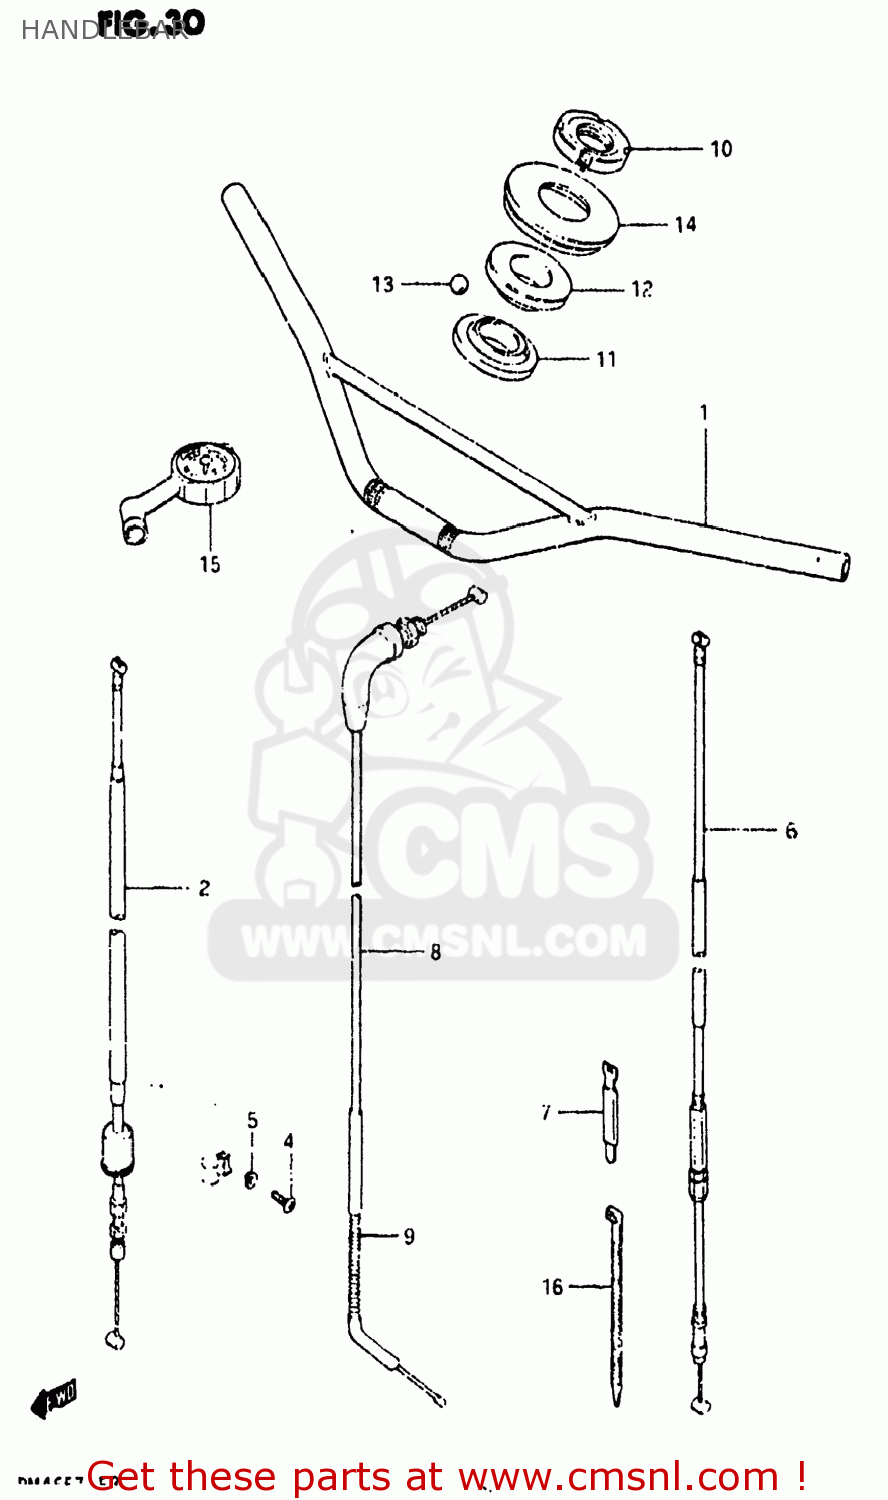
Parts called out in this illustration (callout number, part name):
1	HANDLEBAR
2	CABLE ASSEMBLY,FRONT BRAKE
3	GUIDE,CABLE
4	SCREW
5	LOCK WASHER
6	CABLE ASSEMBLY,CLUTCH
7	CLAMP
8	CABLE ASSEMBLY,THROTTLE
9	PROTECTOR,CABLE
10	NUT,STEERING STEM
11	RACE,STEERING,INNER,UPPER
12	RACE,STEERING,OUTER,UPPER
13	BALL
14	SEAL,STEERING UPR DUST
15	GAUGE ASSY,AIR PRESSURE
16	CLAMP
